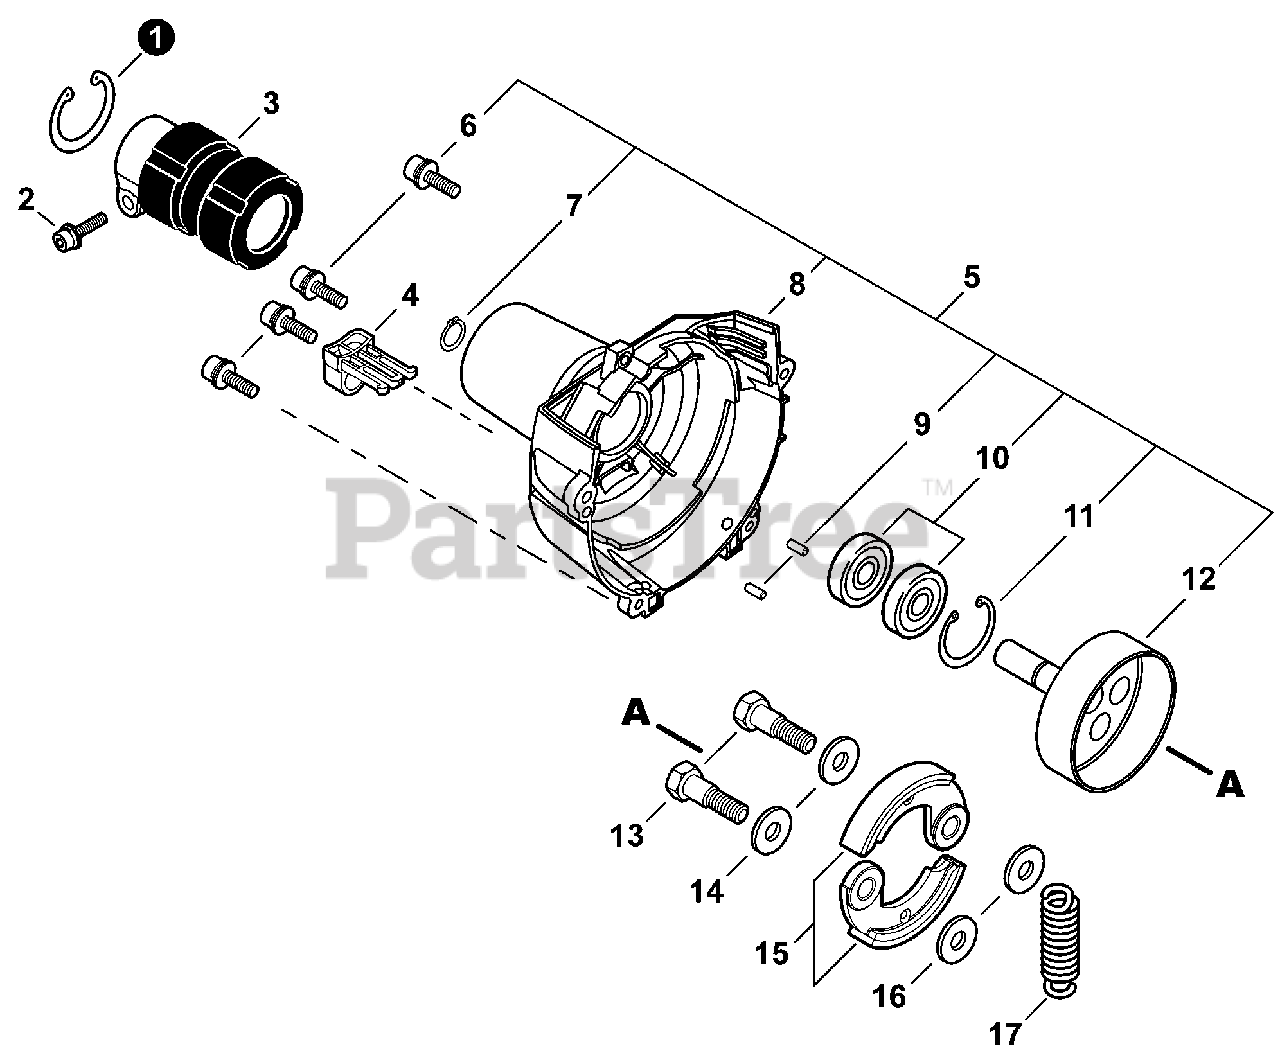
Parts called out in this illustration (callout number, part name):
1	RING, SNAP 42
2	BOLT 5×28
3	HOLDER, MAIN PIPE
5	COVER ASSY, FAN
6	BOLT 4×16
7	RING, SNAP 12
8	COVER, FAN
9	PIN, LOCATING 4
10	BEARING, BALL 6001
11	RING, SNAP 28
12	DRUM, CLUTCH
13	BOLT, CLUTCH 8×7.9×M6
14	WASHER 8.5×16×0.5
15	SHOE, CLUTCH
16	WASHER 6.2×19×1.0
17	SPRING, CLUTCH
